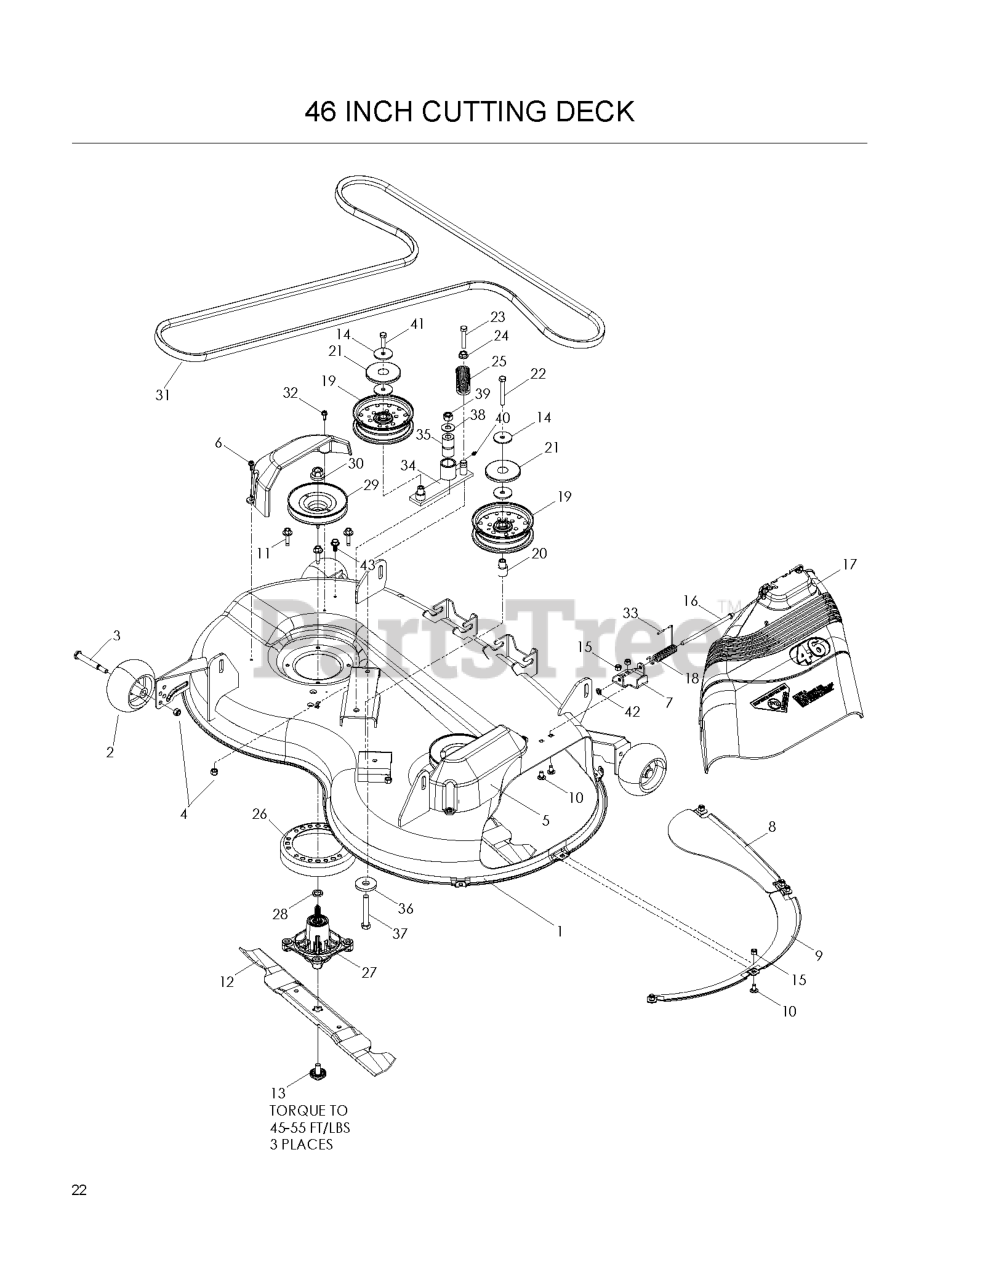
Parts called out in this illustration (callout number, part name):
1	DECK W/DECALS 46" ORANGE
2	GAUGE WHEEL
3	SHOULDER BOLT 1/2X2-5/8 ZD SPE
4	NUT 3/8-16 NYLOC
5	COVER.MANDREL.RH.46"
6	COVER.MANDREL.LH.46"
7	BRKT.DEFLECTOR.38"2005+
8	BAFFLE CENTER FRONT
9	BAFFLE FRONT RH
10	CARRIAGE BOLT 5/16C X 5/8"
11	WASHER HEAD SCREW
12	BLADE, 46" HI-LIFT
13	BOLT.WASHER.ASM.7/16-2
14	WASHER, 3/8 SPEC
15	NUT 5/16 NYLOC
16	ROD, HINGE
17	SHIELD.DEFLECTOR.MOWER.46"BLAC
18	TORSION SPRING
19	IDLER PULLEY
20	IDLER BUSHING
21	TOP DUST CAP
22	HEX SCREW 3/8-20 X 2.75
23	HCS 3/8C X 2
24	NUT 3/8C WHIZ
26	STRIPPER-ROUND-UNIVERSAL
27	CUTTER HOUSING
28	WASHER-SPACER
29	RP.PULLEY, DECK
30	LOCKNUT - 9/16
31	BELT, DECK
32	SCREW- 1/4-20 X 5/8
33	CAP-SLEEVE
35	PIVOT BUSHING
36	WASHER, SUPPORT
37	HCS 1/2C X 3 1/4
38	WASHER 1/2 FLAT
39	NUT 1/2-13 HEX NYLOC ZD
40	ZERK
41	HCS 3/8C X 1 1/4 GR5
42	PUSH NUT
43	SCREW, 3/8-16 X 3/4 THREAD CUT
